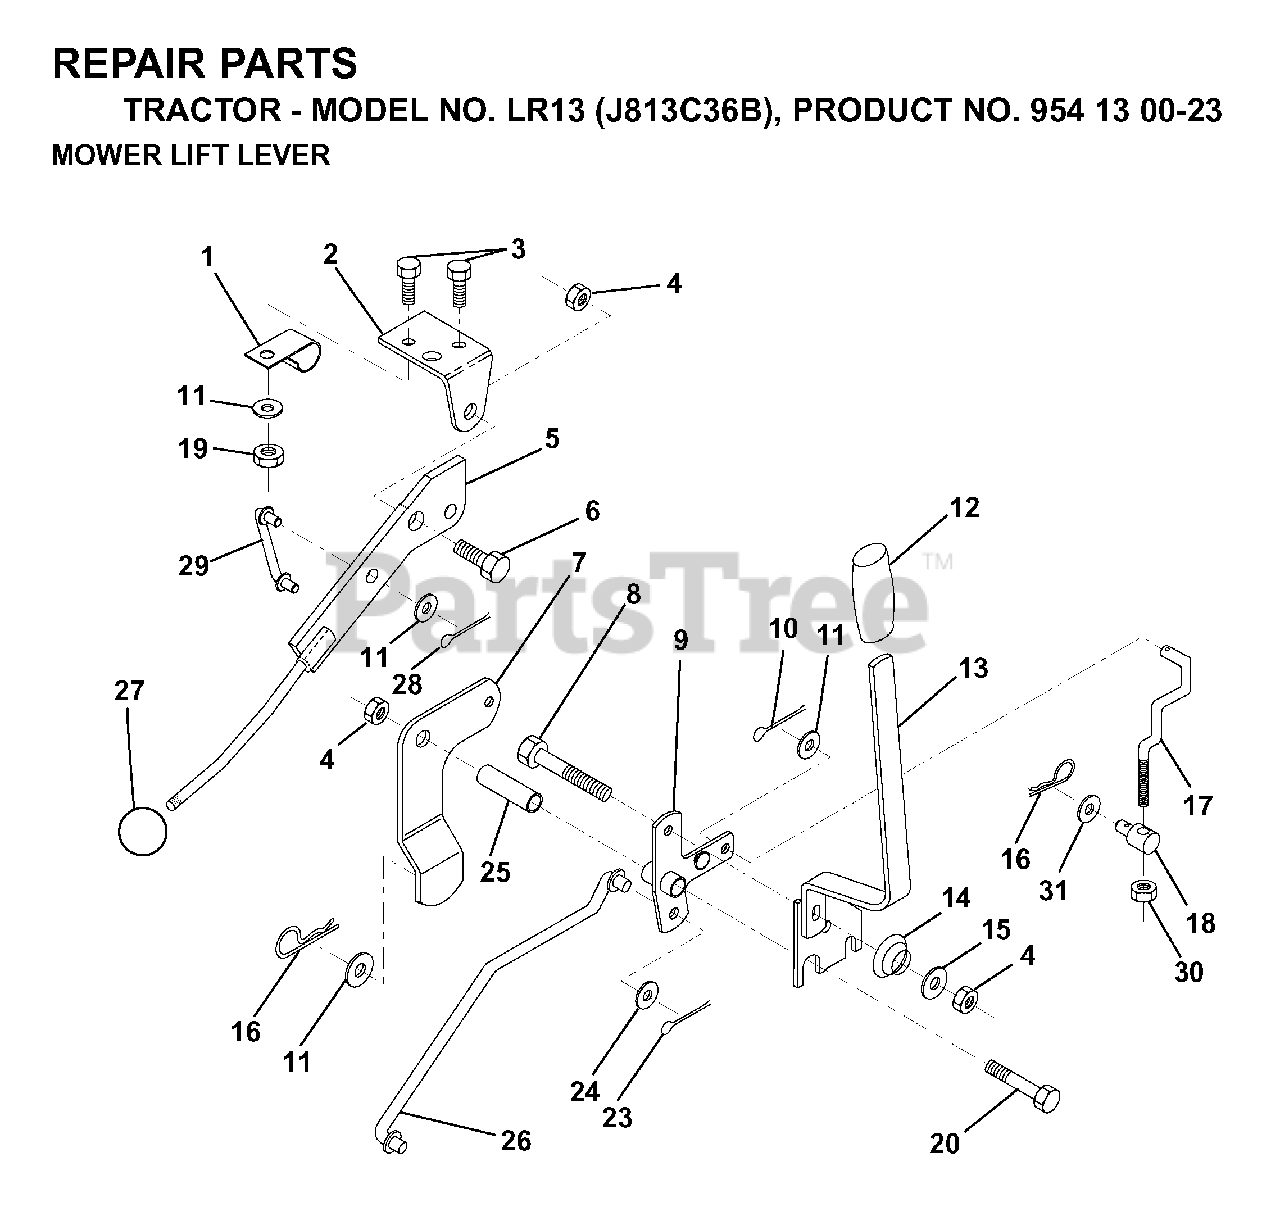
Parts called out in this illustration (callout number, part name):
1	CLIP,INSULATOR
2	BRKT CLUTCH
4	LOCKNUT
5	CLUTCH LEVER
6	BOLT, SHOULDER LT
7	ASSEMBLY MOWER CLUTCH ARM
9	BELLCRANK,LIFT
10	COTTER PIN
12	GRIP HANDLE
13	LIFT HANDLE ASSY
14	SPRING COMPRESSIO
15	WASHER T
16	SPRING TI
17	LINK LIFT FRT
19	NUT.CROWNLOCK.1/4
23	PIN COTTER
24	WASHER GT
25	TUBE SPACER
27	KNOB
28	COTTER PIN
29	LINK MOWER CLUTCH
30	NUT
